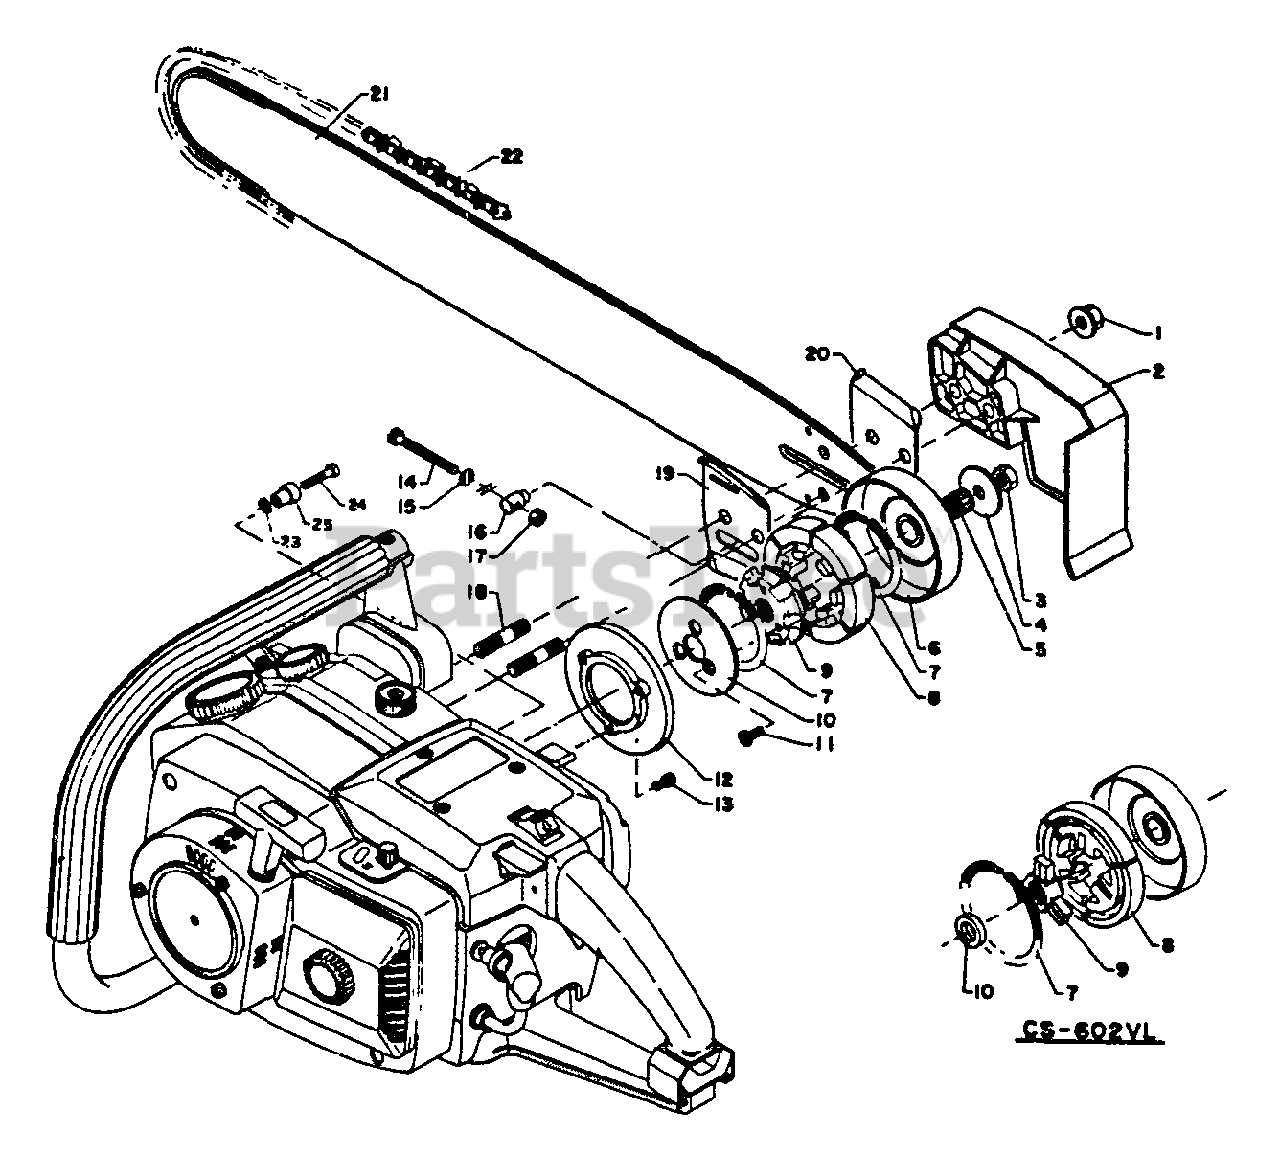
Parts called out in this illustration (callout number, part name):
1	NUT, FLANGE M8×1.25
2	GUARD, SPROCKET
3	LOCKNUT
4	WASHER, CLUTCH
5	BEARING, NEEDLE
6	DRUM, CLUTCH
7	SPRING, CLUTCH
8	SHOE, CLUTCH
8	SPRING, CLUTCH
9	HUB, CLUTCH
10	PLATE, CLUTCH
10	WASHER, CLUTCH
11	SCREW 5×12
12	SEAL, DUST
13	SCREW - 4×10
14	SCREW, ADJUSTER
15	WASHER
16	TENSIONER, CHAIN
17	LOCKNUT - 5
18	STUD, GUIDE BAR
19	PLATE, GUIDE - INNER
20	PLATE, GUIDE - OUTER
21	GUIDE BAR - 60M50
21	GUIDE BAR - 50" (127 CM)
22	SAWING CHAIN - 72LP-84E
22	SAWING CHAIN - 72LP-72E CS-602VL ONLY
23	WASHER, FLAT 5.5×10×0.8
24	SCREW 5×25
25	CATCHER, CHAIN
